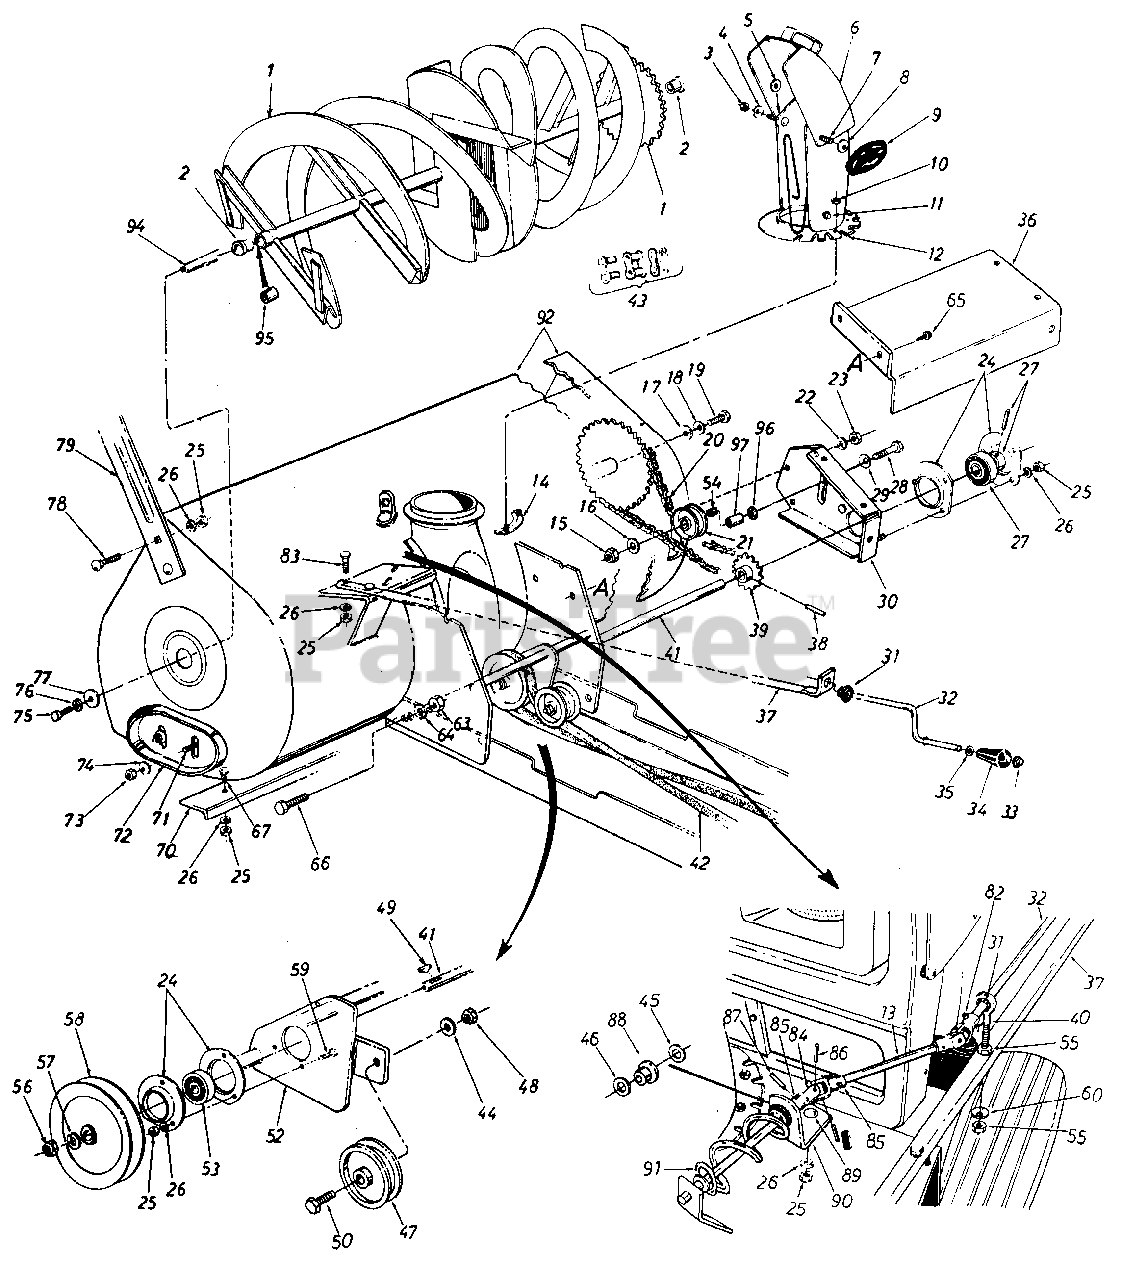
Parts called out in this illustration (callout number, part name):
1	Spiral Ass'y.
2	Flange Bearing
3	Hex Cent. L.-Nut 5/16-18 Thd.
4	Belleville Wash. 3/8" I.D.
5	Flat Washer 3/8" I.D.
6	Top Chute Ass'y.
7	Carriage Bolt 5/16-18 x .62" Lg.
8	Belleville Wash. 3/8" I.D.
9	Hand Knob
10	Hex Cent. L.-Nut 1/4-20 Thd.
11	Push Cap .188" Dia. Rod
12	Chute Ass'y.
13	Chute Crank Extension Rod
14	Chute Flange Keeper Ass'y.
15	L.-Nut 3/8-16 Thd.
18	Belleville Wash.
19	Hex Bolt 1/2-13 x 1.00" Lg.*
20	#420 Chain 1/2" Pitch x 77 Links
21	Plastic Idler 2.00" O.D.
22	L.-Wash. 1/4" I.D.*
23	Hex Nut 1/4-20 Thd.*
24	Bearing Housing
25	Hex Nut 5/16-18 Thd.*
26	L.-Wash. 5/16" I.D.*
27	Self-Aligning Bearing
28	Hex Bolt 3/8-16 x 1.75" Lg.
29	BellevilleWash.3/8" I.D.
30	Chain Guard Ass'y.
31	Nylon Bushing
32	Chute Crank .375 Dia. x 33" Lg.
33	Push Nut 3/8" Rod
34	Knob 3/8" Dia. Hole
35	Flat Washer
36	Drive Shaft Cover
39	14 Teeth Sprocket Ass'y.
40	Eyebolt 5/16-18 x 3.0" Lg.
42	"V"-Belt 1/2" x 88" Lg. (Kevlar)
43	Master Link for #420 Chain
44	L.-Wash. 3/8" I.D.*
45	Fl.-Wash. .385 I.D. x .62" O.D.
46	Fl.-Wash. .390 I.D. x 1.50" O.D.
47	Fl.-ldler with Flanges
48	Hex Jam L.-Nut 3/8-26 Thd.
49	#61 Hi-Pro Key
50	Hex Bolt 3/8-16 x 1.50" Lg.*
52	Spiral Housing Ass'y.
53	Self-Aligning Bearing
54	Sleeve Bearing .50" I.D.
55	Hex Nut 5/16-18 Thd.*
56	Hex Nut 3/4-10 Thd.
57	L.-Wash. 3/4" I.D.
58	"V"-Pulley .750" I.D. x 6.00." O.D.
59	Hex Sems Bolt 5/16-18 x .75" Lg. *
60	Bell.-Wash. .345" I.D. x .88" O.D.
63	Hex L.-Nut 1/2-20 Thd.
64	L.-Wash. 1/2" I.D.*
65	Hex Wash. Hd. Tap Scr. 1/4-20 x.50" Lg. I
66	Hex Bolt 1/2-20 x 1.25" Lg.*
67	Carriage Bolt 5/16-18 x .62"*
72	Skid Shoe
73	Hex Nut 3/8-16 Thd.*
74	BellevilleWash.3/8" I.D.
75	Hex Bolt 1/2-13 x 1.00" Lg.*
76	BellevilleWash. 1/2" I.D.
78	Carriage Bolt 5/16-18 x .62" Lg. *
79	Drift Cutter
83	Hex Bolt 5/16-18 x 1.50" Lg. *
85	Joint Bracket Ass'y.
86	Spring Pin Roll 3/16" Dia. x .75" Lg.*
87	Spring Pin Roll 1/8" Dia. x .75" Lg. *
88	Nylon Bushing
89	Carriage Bolt 5/16-18 x .62
90	Chute Crank Bracket
91	Chute Crank Ass'y.
92	Spiral Housing Ass'y.
95	Sleeve Bearing
97	Idler Spacer
